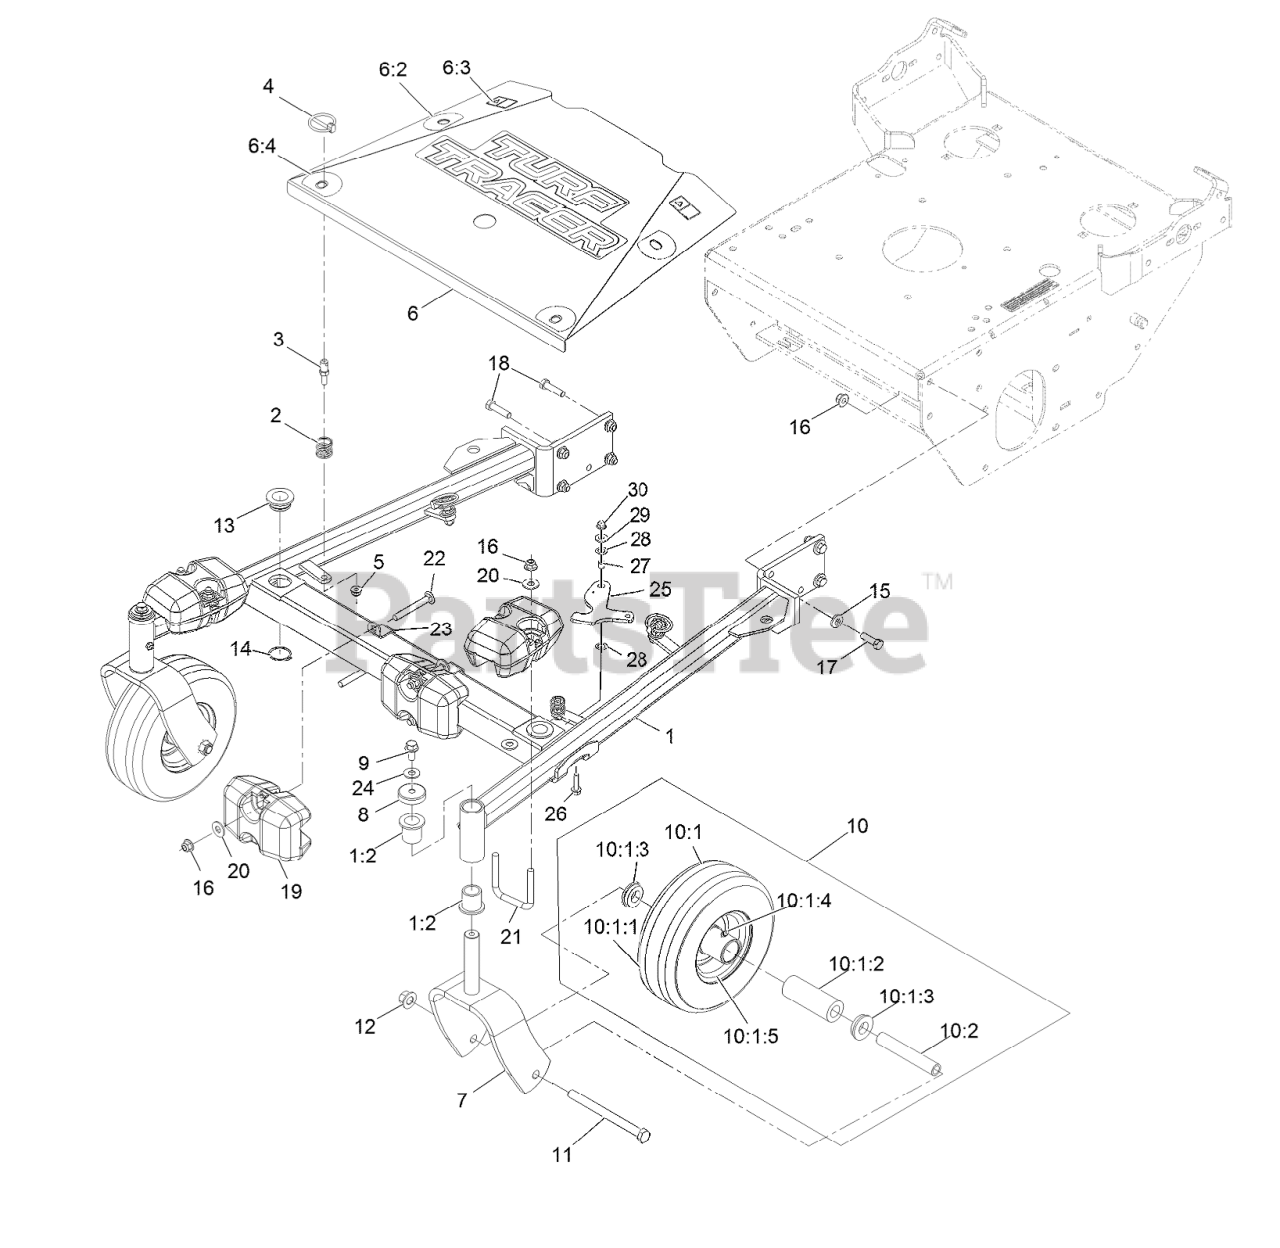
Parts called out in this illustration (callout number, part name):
1	ASM, FRAME W/ BUSHINGS, 4
1:2	BEARING-FLANGED
3	PIN-SPRING
4	PIN-LYNCH
5	NUT-HF, NI
6	ASM, SHIELD W/ DECALS, 48
6:2	DECAL-TURF TRACER
6:3	DECAL-WARNING
6:4	DECAL-SCRATCH COVER
7	FORK, CASTER
8	CAP, DUST
9	SCREW-HHF
10	KIT, SP CASTER WHEEL REPL
10:1	Wheel And Tire ASM
10:1:1	Tire
10:1:2	BEARING
10:1:3	BUSHING
10:1:4	FITTING-GREASE
10:1:5	Wheel
11	SCREW-HH
12	Nut-Lock 1/2-13
13	BUSHING-DECK
14	RING-RETAINING
15	WASHER-BELLEVILLE
16	NUT-HF, NI
17	SCREW-HH
18	SCREW-HH
19	WEIGHT-SUPPORT, CASTER
20	WASHER-FLAT
22	SCREW-CARR
23	STRAP, WEIGHT
25	LATCH, DECK HEIGHT
26	Screw-HHF
27	Spacer-Grommet
28	WASHER-CONICAL
29	WASHER-FLAT
30	NUT-HF, NI
